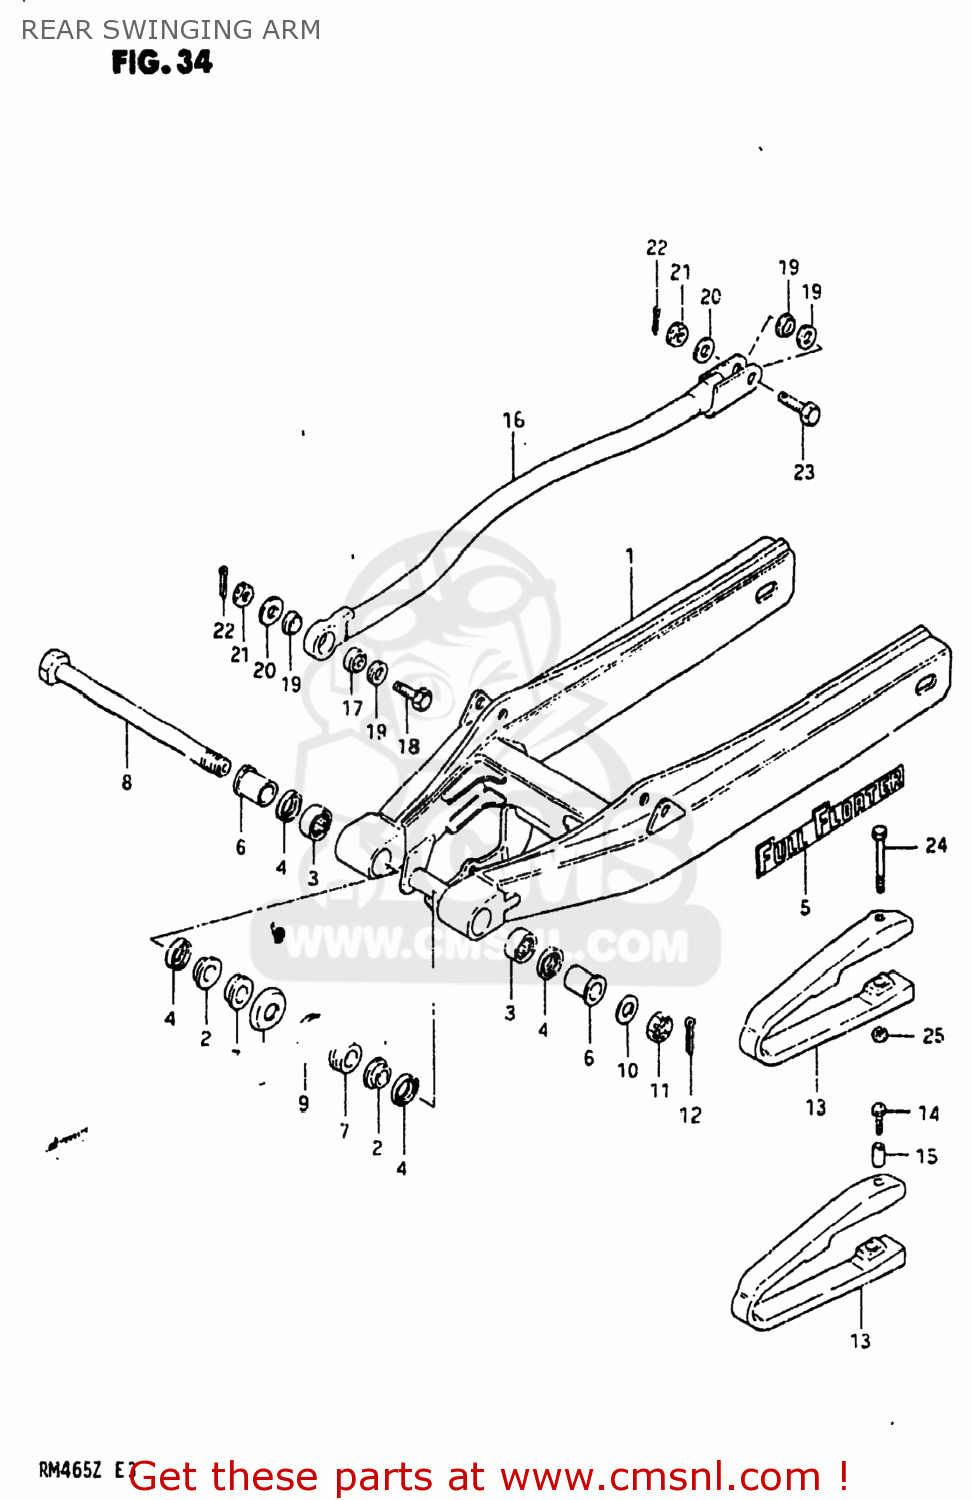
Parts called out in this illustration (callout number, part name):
1	SWING ARM ASSEMBLY,REAR
2	BUSH,RR SWINGINGARM PIVOT
3	BEARING(20X27X20)
4	OIL SEAL
5	EMBLEM,SWING ARM
6	SPACER,RR SWGARM PIVOT
7	SPACER,RR SWGARM PIVOT INNER
8	SHAFT,RR SWINGINGARM PIVOT
9	COVER,RR SWGARM DUST SEAL
10	WASHER
11	NUT 14MM
12	COTTER PIN
13	BUFFER,CHAIN TOUCH DEFLECTOR
14	SCREW,CHAIN TOUCH DEFEND
15	SPACER (5.5X8X4)
16	LINK,REAR TORQUE
17	SPHERICAL BEARING,TORQUE
18	BOLT 8X28
19	20
20	WASHER
21	NUT 8MM
22	PIN 20X20
23	BOLT 8X29.5
24	BOLT
25	NUT
